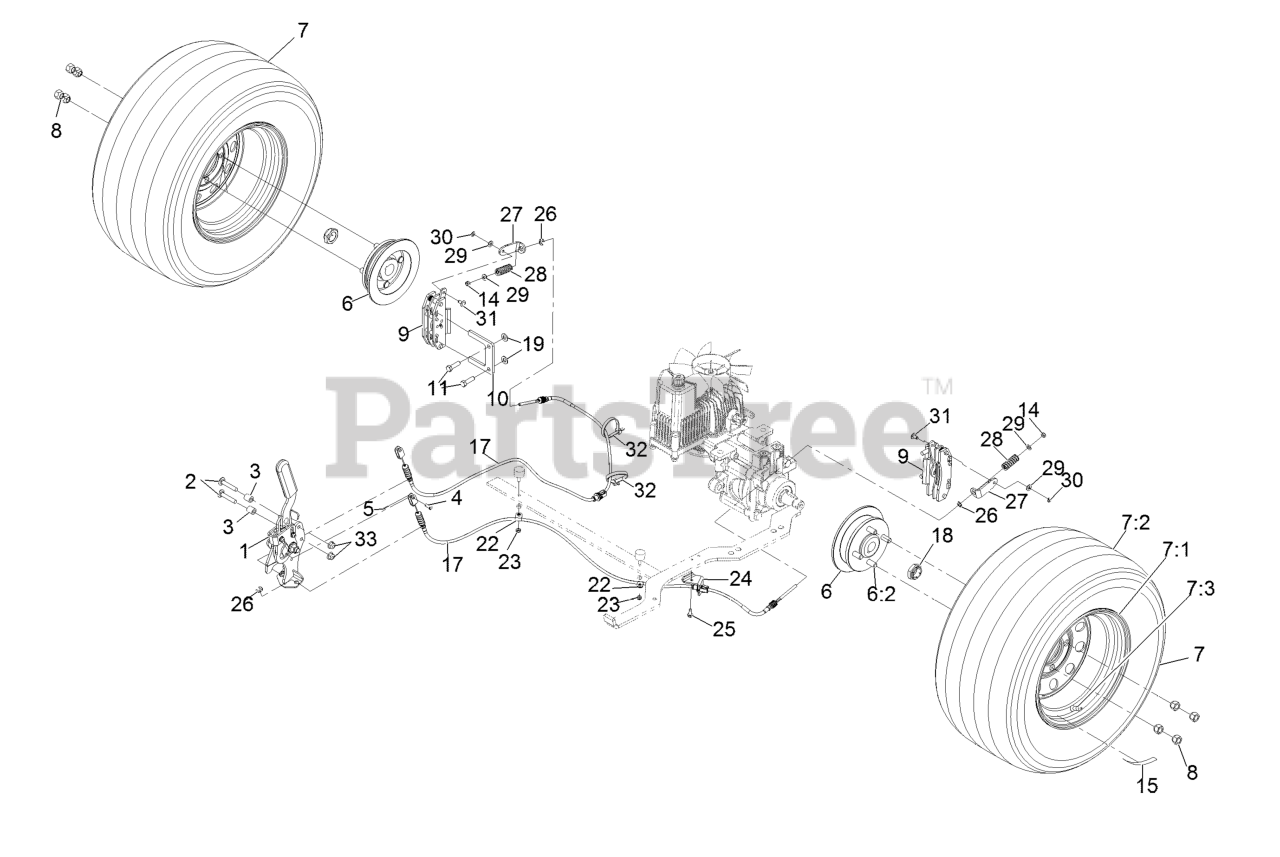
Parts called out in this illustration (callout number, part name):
1	BRAKE HANDLE ASM
2	SCREW-CARR
4	PIN-CLEVIS
5	PIN-COTTER
6	WHEEL HUB ASM
6:2	STUD-WHEEL
7	WHEEL AND TIRE ASM
7:3	Stem-Valve
8	NUT-LUG
9	CALIPER-BRAKE
10	PLATE-MOUNT, BRAKE
11	SCREW-LOCK, PATCH
14	NUT-LOCK, NI
17	CABLE-BRAKE
18	LOCKNUT
19	WASHER-FLAT
23	NUT-LOCK, NI
24	BRACKET-CABLE
25	SCREW-HWH
27	BRACKET-BRAKE, L
28	SPRING-DIE
29	WASHER-FLAT
31	PIN-BRAKE
32	TIE-CABLE
33	NUT-HF, NI
